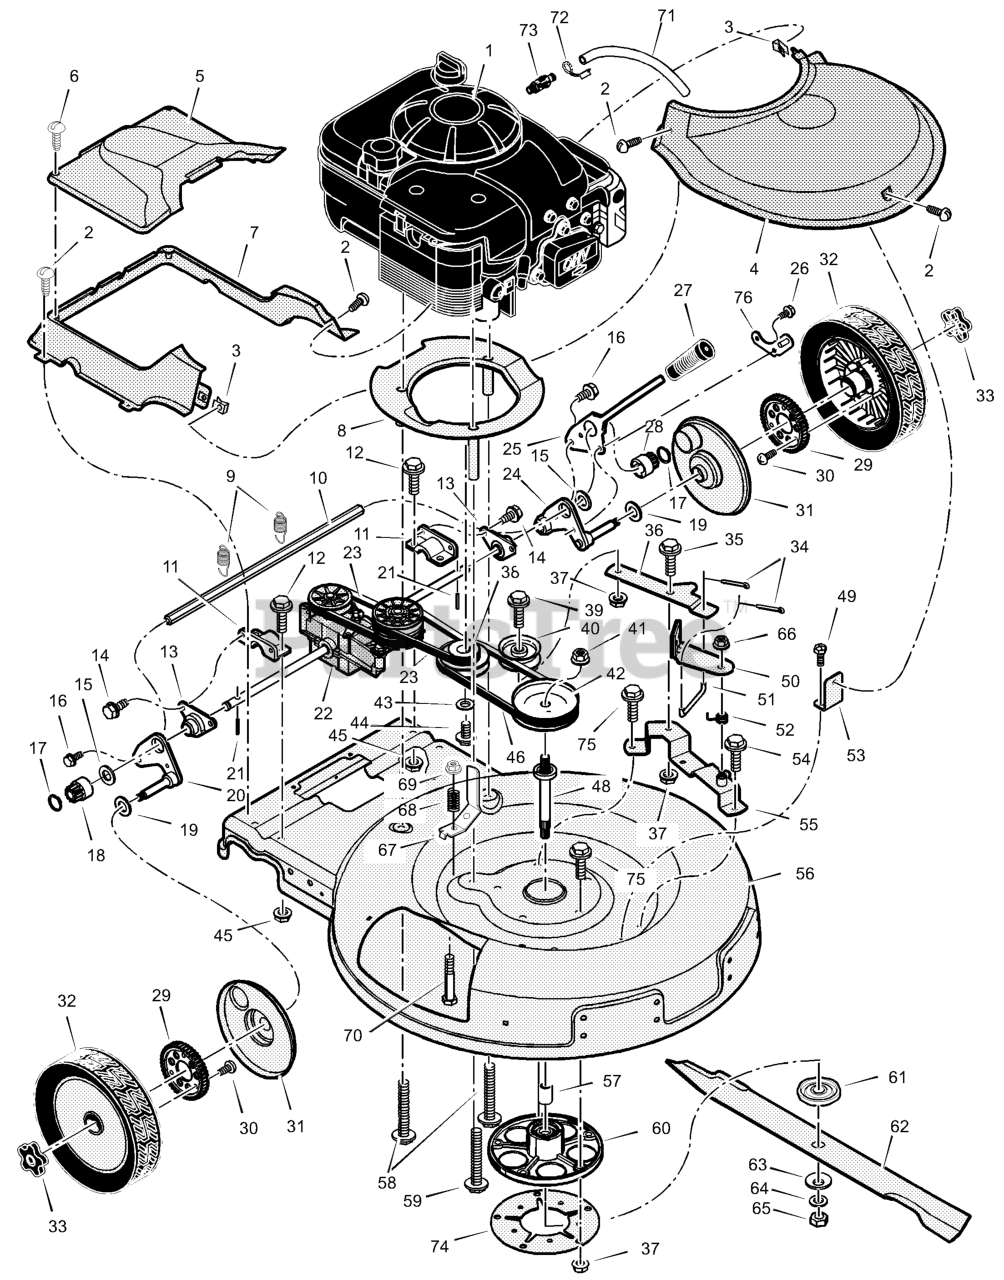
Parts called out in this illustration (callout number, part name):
1	Engine
3	Tinnerman, "U"
4	Cover, Front
5	Cover, Transmission
7	Cover, Rear
8	Base Assembly, Engine
9	Spring, Extension
10	Crossbar, Rear
11	Bearing, Axle Support
12	Screw
13	Retainer Assembly, Axle Bearing
15	Washer, Thrust
17	Retainer Ring
18	Gear, Right Pinion
19	Washer, Spring
20	Bracket Assembly, Right Axle
21	Pin, Drive
22	Transmission *
23	Belt, Transmission
24	Bracket Assembly, Left Axle
25	Lever, Spring Height Adjuster
26	Screw, Tap
27	Knob, Height Adjuster
28	Gear, Left Pinion
30	Screw, Tap
31	Cover, Dust
32	Wheel, Drive
33	Knob, Axle
34	Pin, Cotter
35	Bolt, Shoulder
36	Idler Arm
37	Nut, Flange
38	Pulley, Engine
39	Screw
40	Pulley, Idler
41	Nut, Blade Pulley
42	Pulley, Blade
43	Washer, Split
44	Screw
46	Belt, Blade Drive
48	Jackshaft
50	Brake Assembly, Blade
51	Link, Blade Brake
52	Spring, Torsion
53	Bracket, Front Cover
55	Support Assembly, Idler & Brake
57	Spacer, Jackshaft
58	Bolt, Short Engine Mount
59	Bolt, Long Engine Mount
60	Mandrel Assembly
61	Adapter, Blade
63	Washer, Cup
65	Nut, Blade Mount
66	Nut
67	Guide, Belt
69	Nut
71	Tube, Oil Drain
72	Cap, Oil Drain
73	Valve, Oil Drain
74	Support, Jackshaft Housing
76	Bracket Assembly, Lifter
